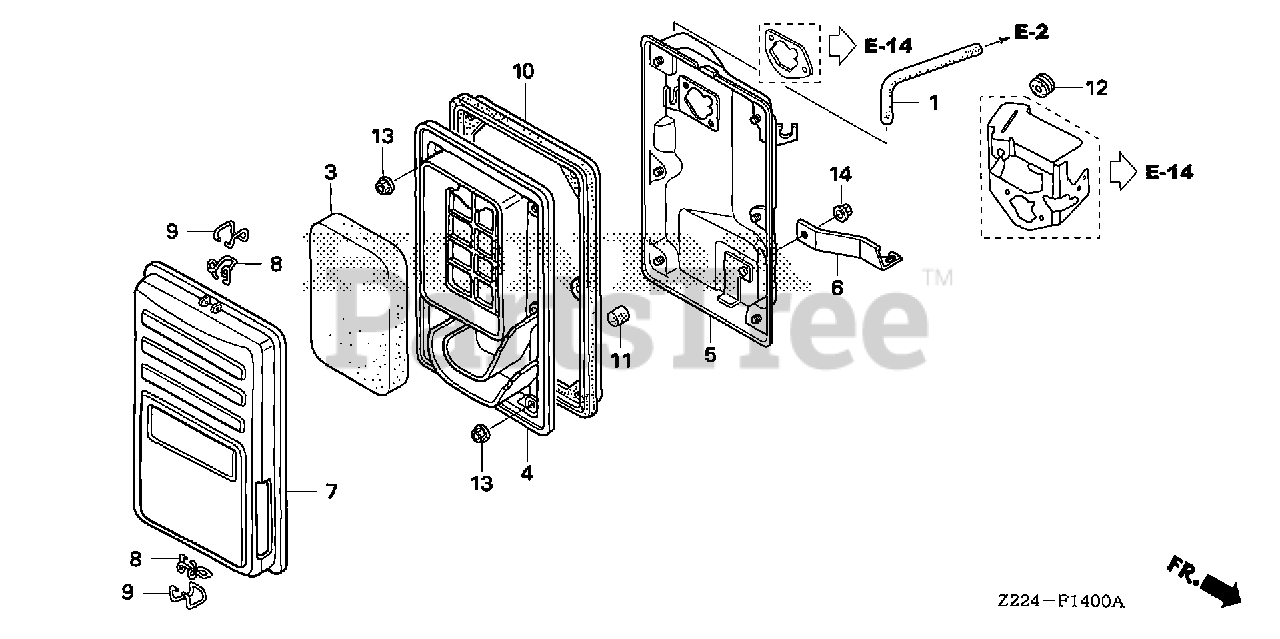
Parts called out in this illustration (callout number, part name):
1	TUBE, BREATHER
3	ELEMENT, AIR CLEANER
4	SEPARATOR, AIR CLEANER
5	HOUSING, AIR CLEANER
6	STAY, AIR CLEANER
7	COVER, AIR CLEANER
8	CLIP A, AIR CLEANER WIRE
9	CLIP B, AIR CLEANER WIRE
10	SEAL, AIR CLEANER
11	FILTER, DRAIN TUBE
12	GROMMET, FENDER
13	NUT, FLANGE (5MM)
14	NUT, FLANGE (6MM)
